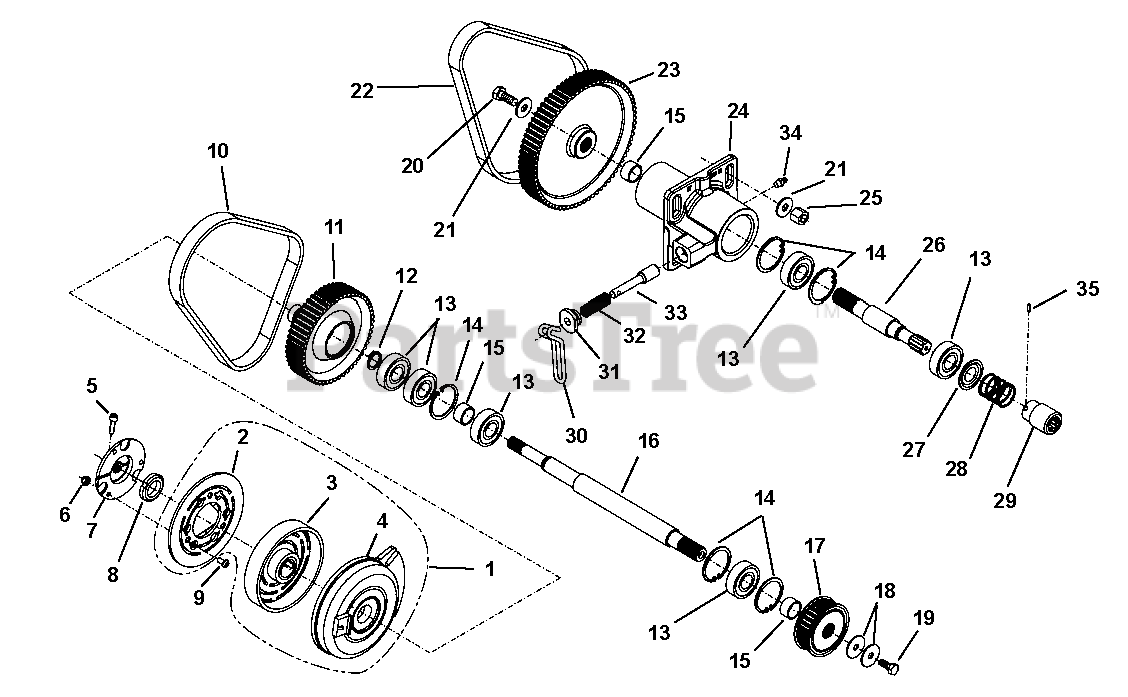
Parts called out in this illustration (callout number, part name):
1	Clutch, Magnet Positive (contains items 2, 3 and 4)
2	Plate, Ancher
3	Rotor
4	Clutch Bellhousing
5	Screw, M6 x 20
6	Nut, Lock D985 M6
8	Nut, Groove M24 x 1.5
9	Screw, M6 x 12 ISO7380
10	Belt, Toothed
12	Circlip, D471 20 1.75
13	Ball Bearing, 6204 2RS /20 x 47 x 14
14	Circlip, D472 47 1.75
16	Shaft, Clutch
18	Washer, Friction
19	Bolt, Hex D933 M8 x 20
20	Bolt, Hex D933 M10 x 25
21	Washer, M10
22	Belt, Toothed L=800 B=20
24	Case, P.T.O.
25	Nut, Hex D6330B M10 x 25
26	Shaft, Clutch
27	Ring, Nilos N545 6204 ZAV
28	Spring, Pressure 2.25/29.75 x 47.90
31	Bolt, CF 3851
32	Spring, Pressure
33	Bolt, Lock
34	Lubricator
35	Pin, Parallel
